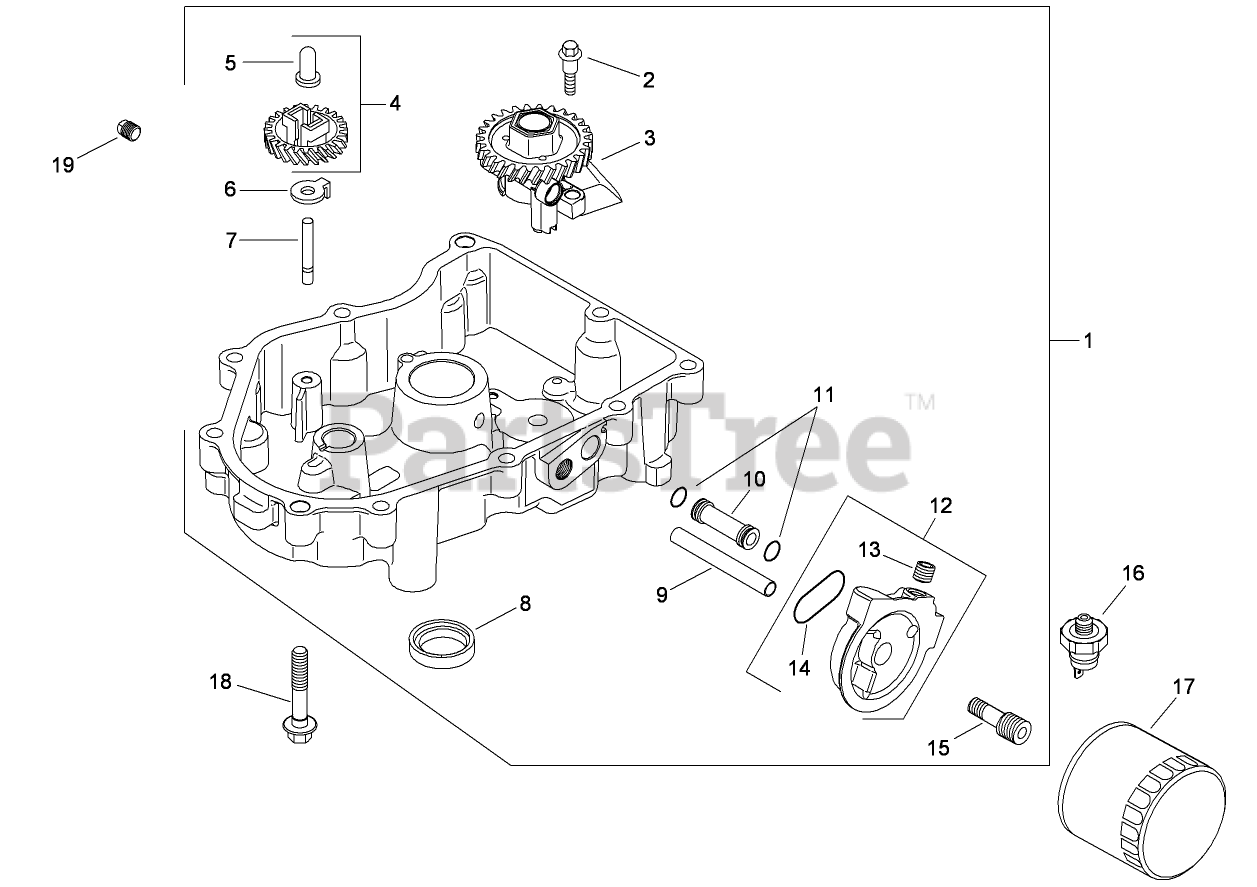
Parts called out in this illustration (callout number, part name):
1	OIL PAN ASM (INCLUDES 2-15)
2	SCREW-SHOULDER, THD FRM (M6x1.0x26.5)
3	OIL PUMP ASM
4	GOVERNOR GEAR KIT W/PIN (INCLUDES 5)
5	PIN-REGULATING, GOVERNOR
6	TAB-LOCKING
7	SHAFT-GEAR, GOVERNOR
8	SEAL-OIL
9	TUBE-FEED, OIL (FILTER TO PAN)
10	TUBE-FEED, OIL (PAN TO FILTER)
11	O-RING
12	ADAPTER OIL FILTER KIT
13	PLUG-PIPE, COUNTERSUNK (1/8)
14	O-RING
15	NIPPLE-FILTER, OIL
16	SWITCH-PRESSURE, OIL
17	FILTER-OIL
18	SCREW-FLANGE (M8X1.25X45)
19	PLUG-PIPE, SQ HD (3/8)
